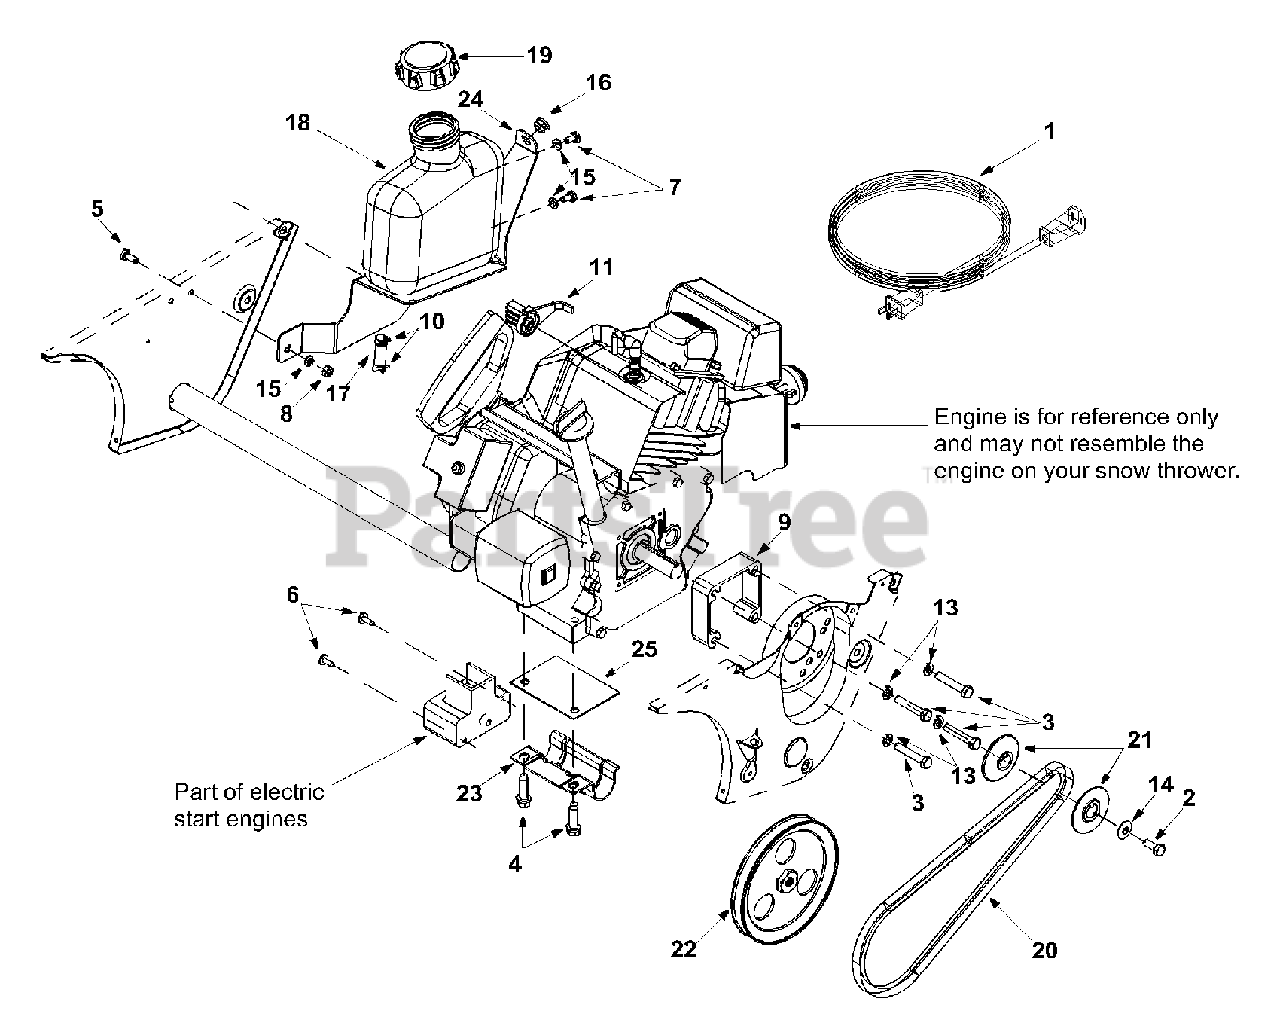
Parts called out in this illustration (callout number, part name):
1	Extension Cord
2	Hex Bolt 5/16-24 x 0.75"
3	Hex Bolt 5/16-24 x 1.75"
4	TT Sems Screw
5	Hex Screw 1/4-20 x 0.620"
6	B Screw #10-16 x 0.625"
7	Hex Screw 1/4-20 x 0.50"
8	Hex Nut 1/4-20
9	Spacer
10	Hose Clamp
11	Choke Knob
13	Lock Washer
14	Beleville Washer
15	Lock Washer
16	Plastic Bushing
17	Fuel Line Hose
18	Gas Tank
19	Fuel Cap
20	V-Belt
21	V-Pulley Half
22	Pulley
